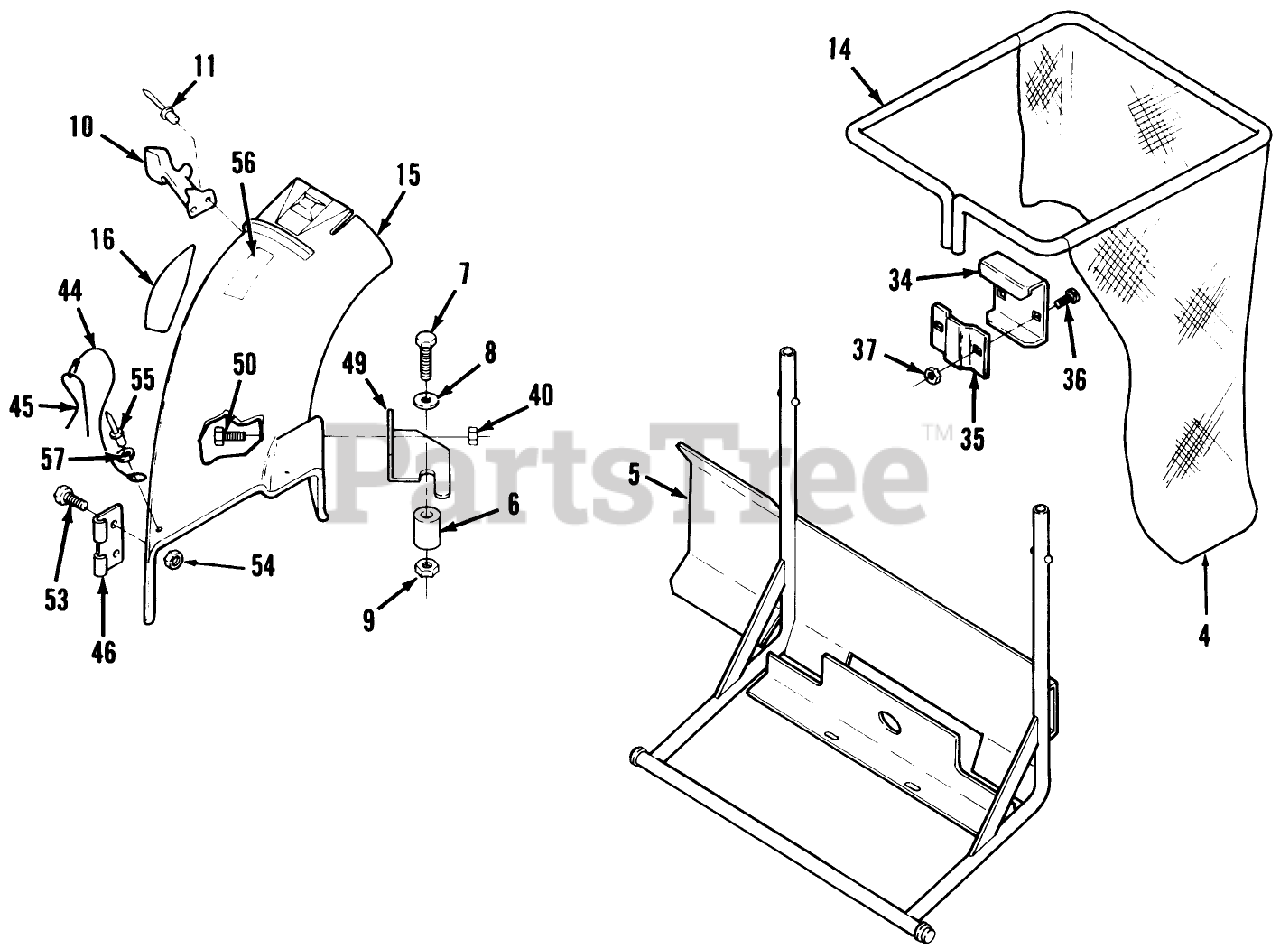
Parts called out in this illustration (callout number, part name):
4	Bag
5	WLDMT-BAGGER RODS B
6	SPACER
7	SCREW-HH
8	Washer
9	NUT-LOCK, NI
10	Latch-38"
11	NUT-LOCK, NI
14	Bag Frame
15	Chute Assembly (Incl. Ref. #10-11, 16, 44-46 & 53-57)
16	Decal-Danger
34	Bag Hanger
35	Clamp
36	BOLT-CARR
37	NUT-LOCK, NI
40	NUT-LOCK, NI
44	LANYARD
45	PIN-LOCKING, CHUTE
46	BRACKET-MOUNTING, CHUTE
49	LATCH-BAGGER ELBOW
50	Bolt
53	Bolt
54	NUT-LOCK, NI
55	RIVET-POP
56	DECAL-DANGER
57	Washer
